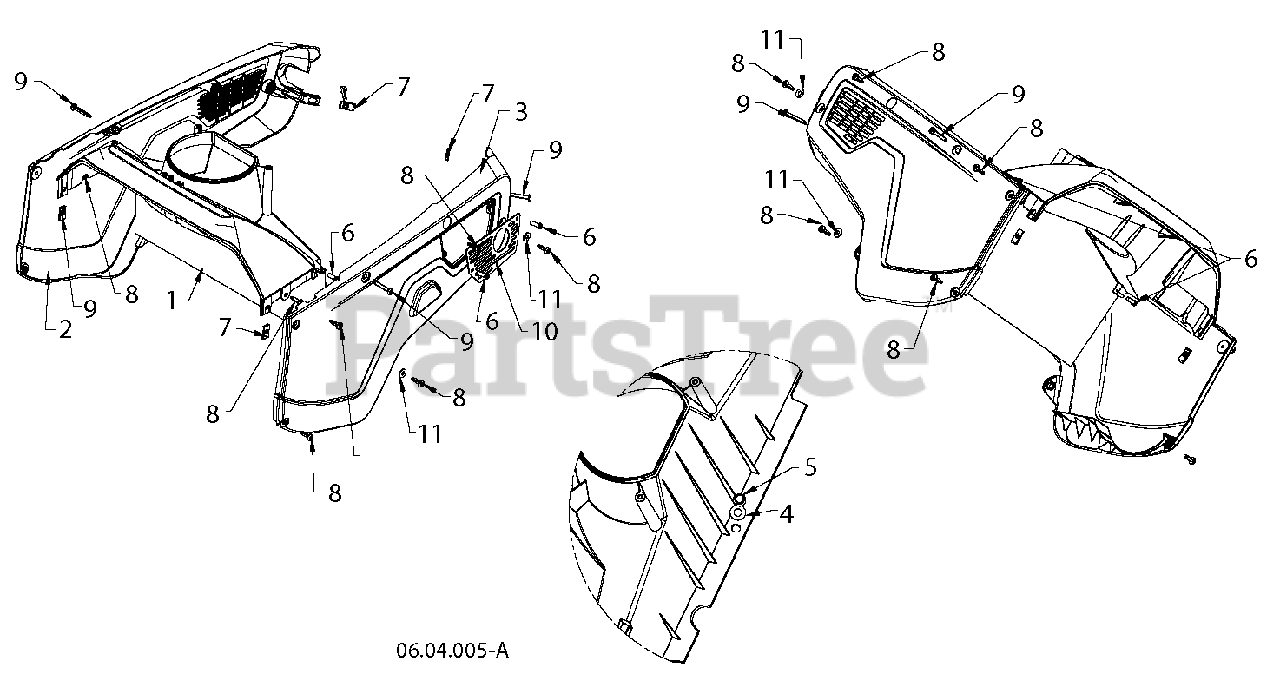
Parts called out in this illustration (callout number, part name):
1	AUGER.PLENUM.SINGLE.STAGE.GREY
2	COVER.NON-DRIVE.SIDE.HUSQ.GRAY
3	COVER.DRIVE.SIDE HUSQVARNA.SNO
4	WASHER
5	BOLT.HEX.HD.WASHER.5/16-18X.75
6	SCREW.HX.13X.750
8	SCREW.PAN.HD.TORX.1/4-20X.750
9	SCREW.1/4-20.PAN.HEAD.TORX.
10	PLATE.EXHAUST.SINGLE.STAGE.SNO
